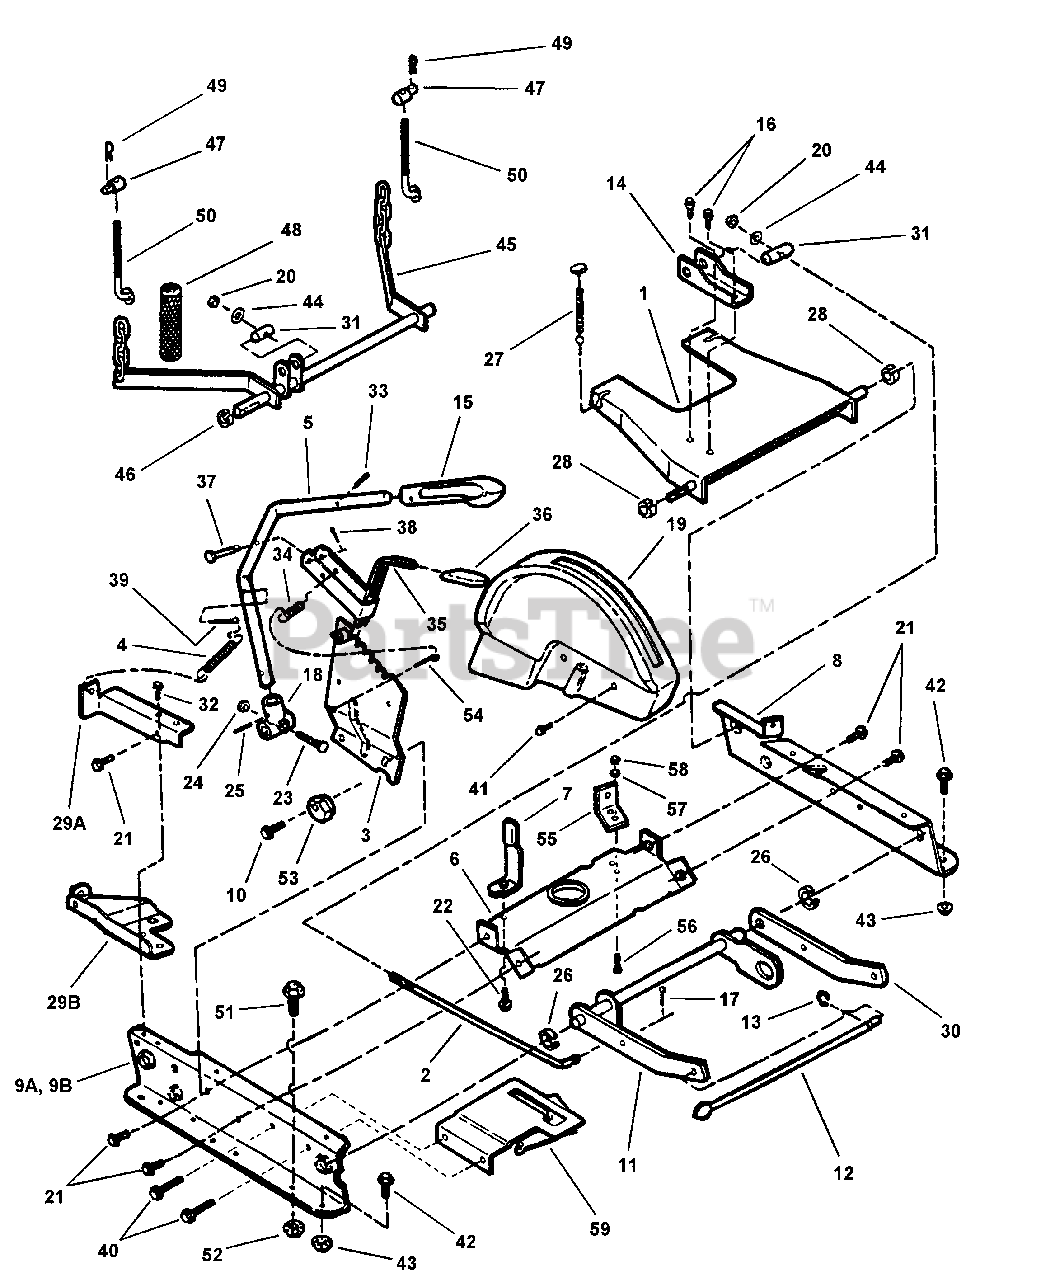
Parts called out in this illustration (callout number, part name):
1	ARM, Rear Lift
2	ROD, Leveling
3	QUADRANT, Lift Lever
4	SPRING, Extension
5	LEVER, Lift
6	BRACE, Top
7	GUIDE, Belt
8	RAIL, Left Hand
9A	RAIL, R.H.
9B	RAIL, R.H.
10	SCREW, 3/8-16 x 1" Hex Washer Self-Tap
11	ARM, Front Lift, Adjustable
12	ROD, Support
13	SNAP RING, 7/16" External
14	ARM, Leveling
15	GRIP, Height Adjustment Lever
16	SCREW, 5/16-18 x 5/8" Truss Head Self-Tap (Torx)
17	PIN, 1/8 x 3/4" Cotter
18	HUB, Deck Lift
19	COVER, Height of Cut
20	NUT, 3/8-24 Hex Nyloc
21	SCREW, 3/8-16 x 5/8" Hex Washer Self-Tap
22	SCREW, 5/16-18 x 5/8" Hex Washer Self-Tap
23	BOLT, 5/16-24 x 1-5/8" Tapered Axle
24	NUT, 5/16-24 Hex Flange Lock
25	PIN, 3/16 x 1" Roll
26	RING, Red
27	CABLE, Rear Deck
28	RING, White
29A	BRACKET, Deck Lift
29B	BRACKET, Lift Assist
30	ARM, Front Lift-Left
31	PIVOT, Leveling
32	SCREW, 1/4-20 x 3/4" Hex Washer Self-Tap
33	PIN, 3/16 x 3/4" Roll
34	SPRING, Latch
35	LATCH (Weldment)
36	GRIP, Lift Latch
37	PIN, 1/4 x 1-1/4" Clevis
38	COTTER-PIN, 1/16 x 3/4"
39	COTTER-PIN, 3/16 x 1-1/2"
40	SCREW, 5/16-18 x 1/2" Hex Washer Self-Tap
41	SCREW, 1/4-20 x 5/8" Hex Washer Self-Tap
42	BOLT, 5/16-18 x 5/8" Hex Flange Lock
43	NUT, 5/16-18 Hex Flange Lock
44	WASHER, 3/8" Flat
45	ARM, Rear Lift
46	RING, Blue
47	SWIVEL
48	COVER, Chain
49	HAIRPIN, 3/32 x 1-1/2"
50	HOOK, Chain
51	BOLT, 1/4-20 x 1/2" Hex Flange Lock
52	NUT, 1/4-20 Hex Flange Lock
53	ECCENTRIC
54	COTTER-PIN, 3/16 x 3/4"
55	ANCHOR
56	SCREW, 5/16-24 x 3/4" Hex Head Cap, Grade 5
57	WASHER, 5/16 Internal Tooth Lock
58	NUT, 5/16-24 Hex
59	ASSEMBLY, Clutch Plate
